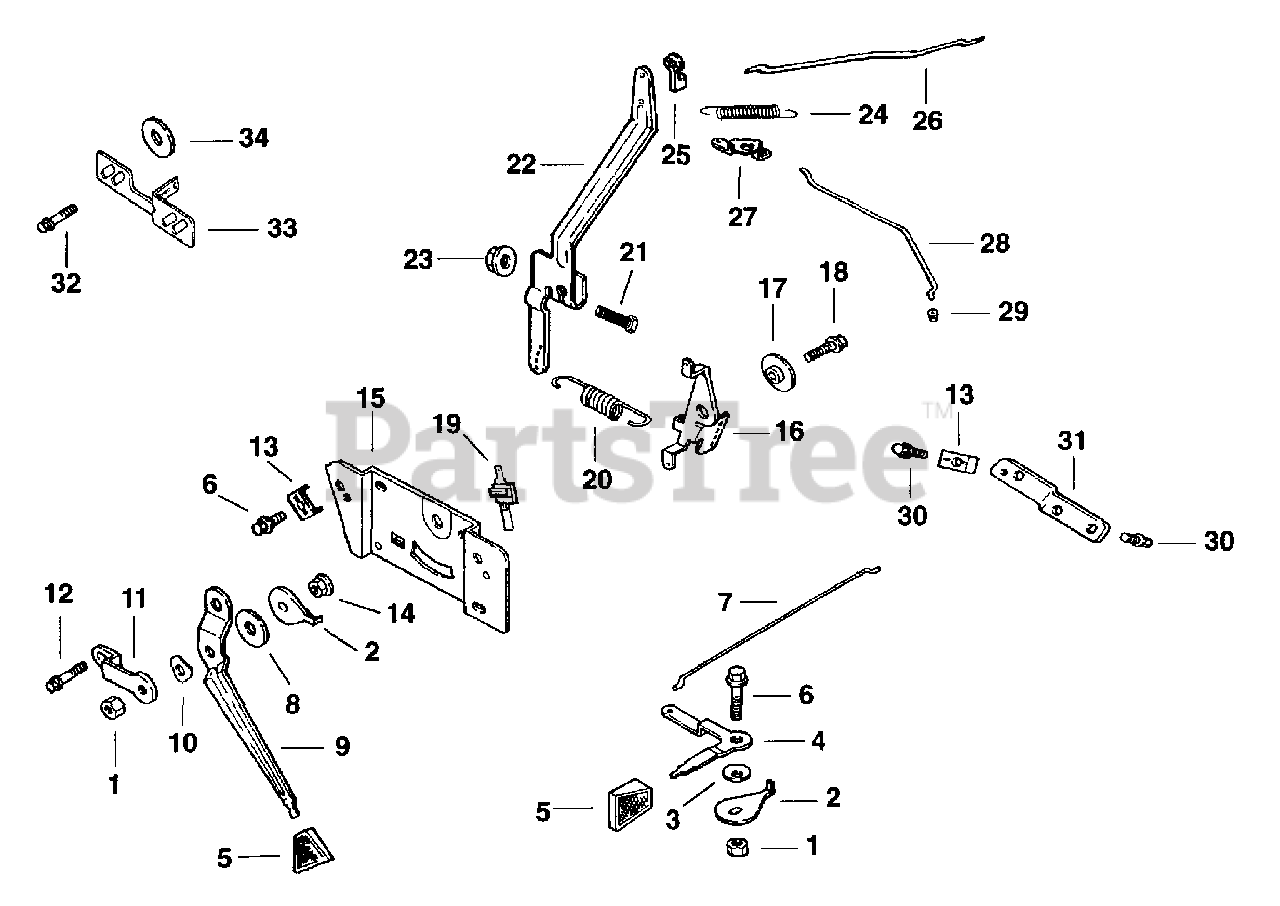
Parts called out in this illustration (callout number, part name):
1	Nut, hex. lock M5x0.8
2	TAB - DISCONTINUED
3	WASHER, SPRING 1/4"
4	LEVER, CHOKE
6	SCREW - USE M-545016
12	SCREW - USE M-645016
13	CLAMP, CABLE
14	Nut, hex. flange M5x0.8
15	PLATE - DISCONTINUED
17	SPACER, CONTROL ASSEMBLY
21	USE SM-642025-S
22	LEVER, GOVERNOR - USE 12 090 40-S
23	Nut, hex. flange M6x1.0
25	BUSHING, THROTTLE LINKAGE
28	LINKAGE - USE 12 079 08
29	BUSHING, LINKAGE RETAINING
30	Screw, hex. flange M5x0.8x10
